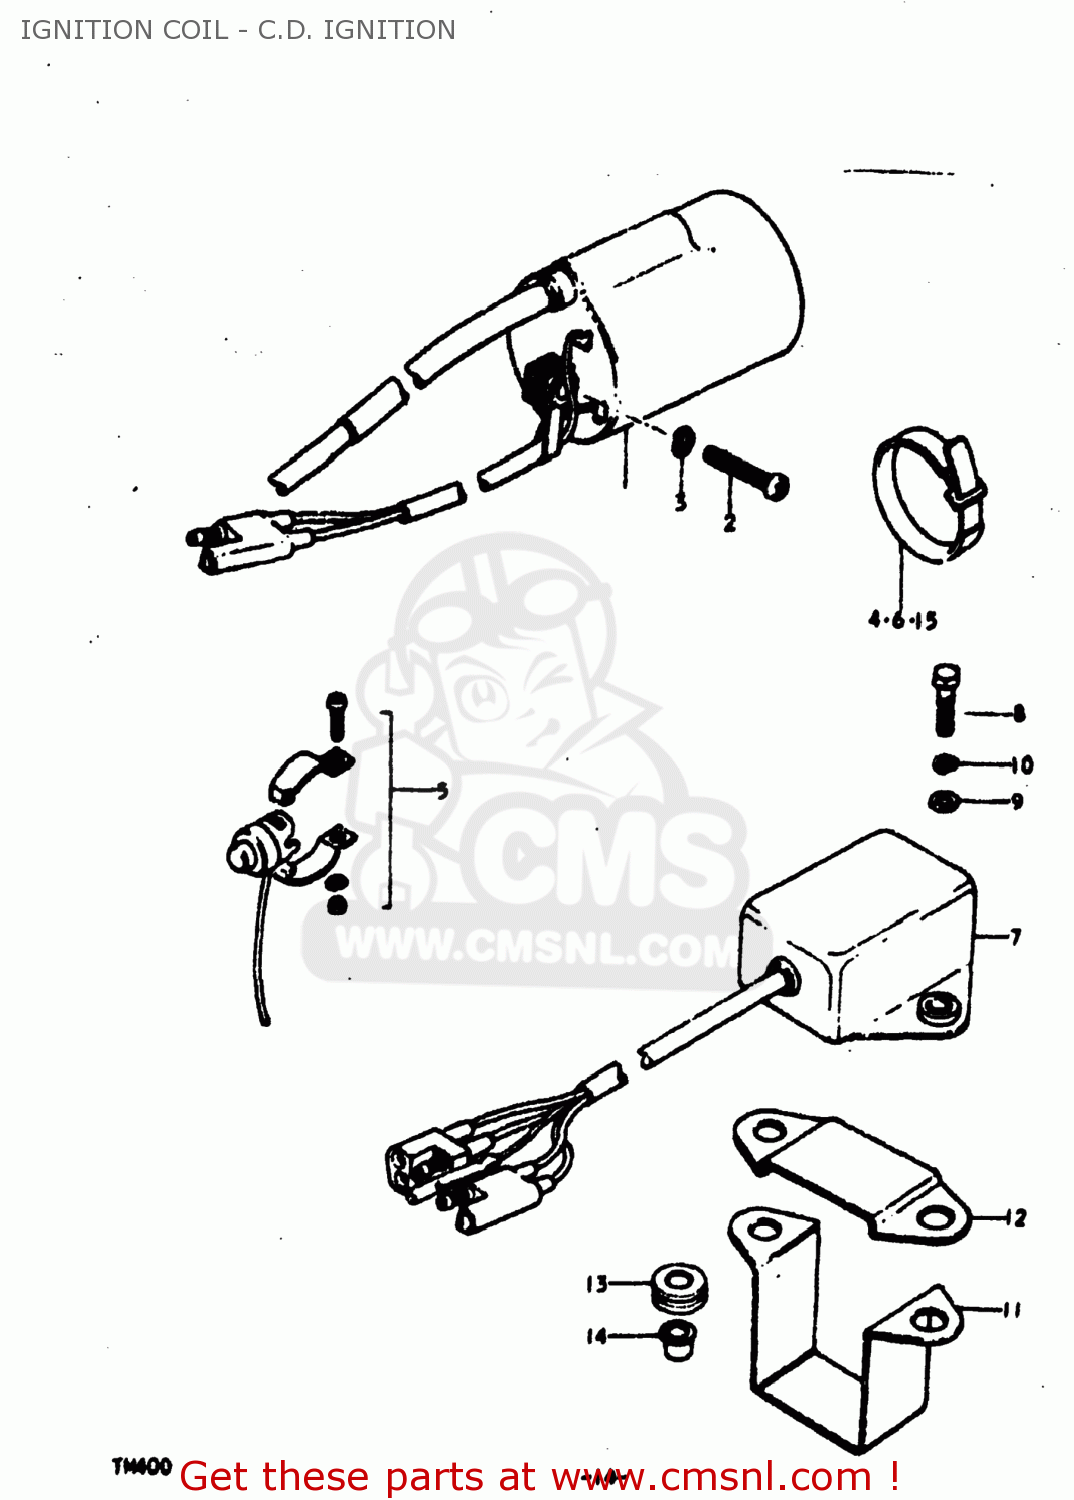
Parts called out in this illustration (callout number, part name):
1	COIL ASSEMBLY,IGNITION
2	SCREW
3	LOCK WASHER
4	CLAMP(L:120)
5	SWITCH ASSEMBLY
6	CLAMP
8	BOLT
9	WASHER 6MM
10	LOCK WASHER
13	CUSHION
14	WASHER
15	CLAMP
